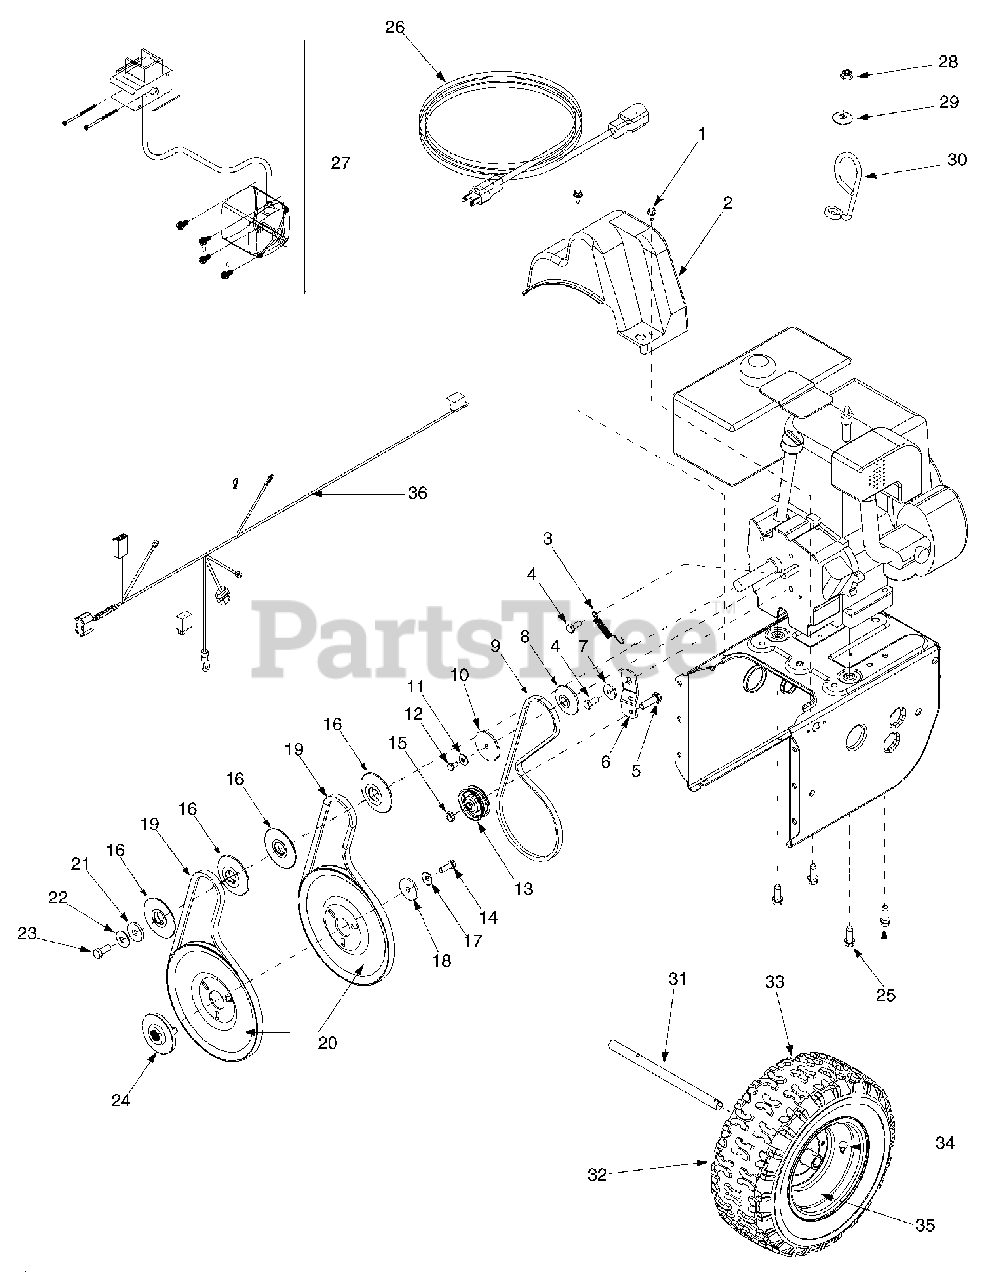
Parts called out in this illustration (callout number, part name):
1	Hex Washer Screw 1/4-20 x .625
2	Belt Cover
3	Extension Spring
4	Hex Screw 5/16-24 x .75
5	Hex Cap Screw 3/8-16 x 1.25
8	Pulley Half
9	V-Belt
10	Pulley Half
11	Bell Washer
12	Hex Cap Screw 1/4-28 x .50
13	Flat Idler
14	Lock Hex Cap Screw 5/16-24
15	Lock Jam Nut 3/8-16
16	Pulley Half
17	Bell Washer
18	Flat Washer
19	Belt
20	Auger Pulley
21	Flat Washer 3/8 x 1.25 OD
22	Bell Washer
23	Hex Cap Screw 3/8-24
24	Adapter Pulley
25	Hex Screw 3/8-16 x 1.0
26	Extension Cord
27	Electric Start Kit
28	Lock Nut, 1/4-20
29	Flat Washer, .28 x .74 x .063
30	Cable Guide
31	Axle 16"
33	Tire 16.0" x 6.50" x 8.0"
34	Tubeless Air Valve
